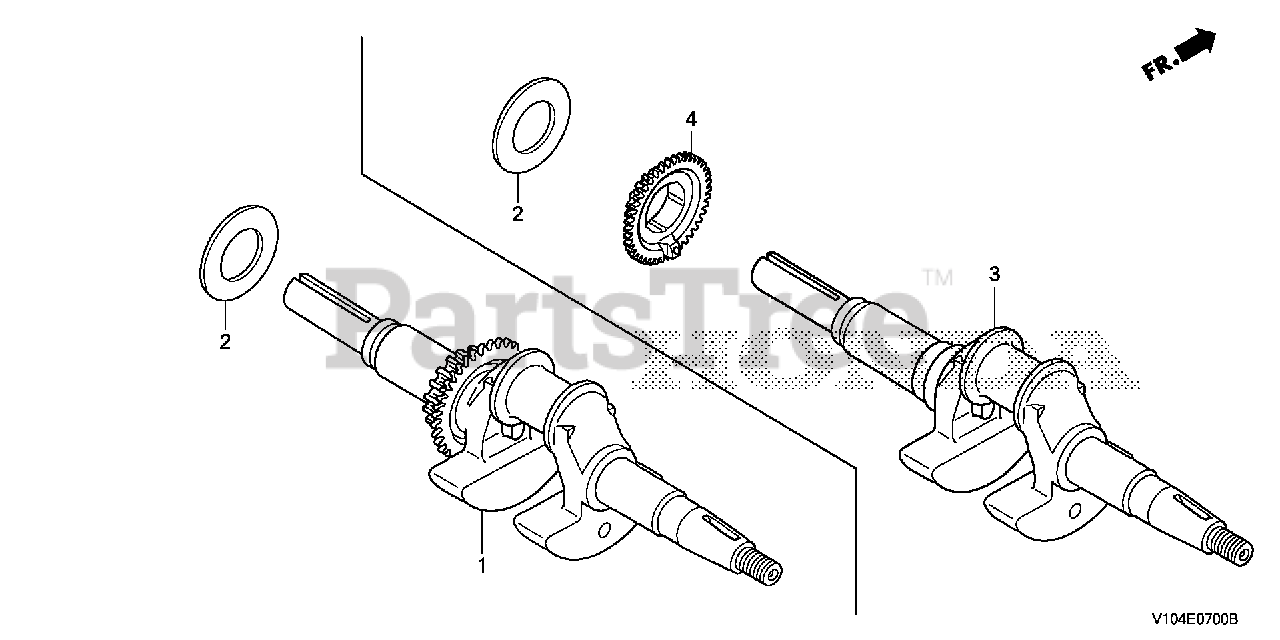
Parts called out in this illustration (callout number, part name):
2	WASHER, THRUST
3	CRANKSHAFT
4	PULLEY, TIMING BELT DRIVE
